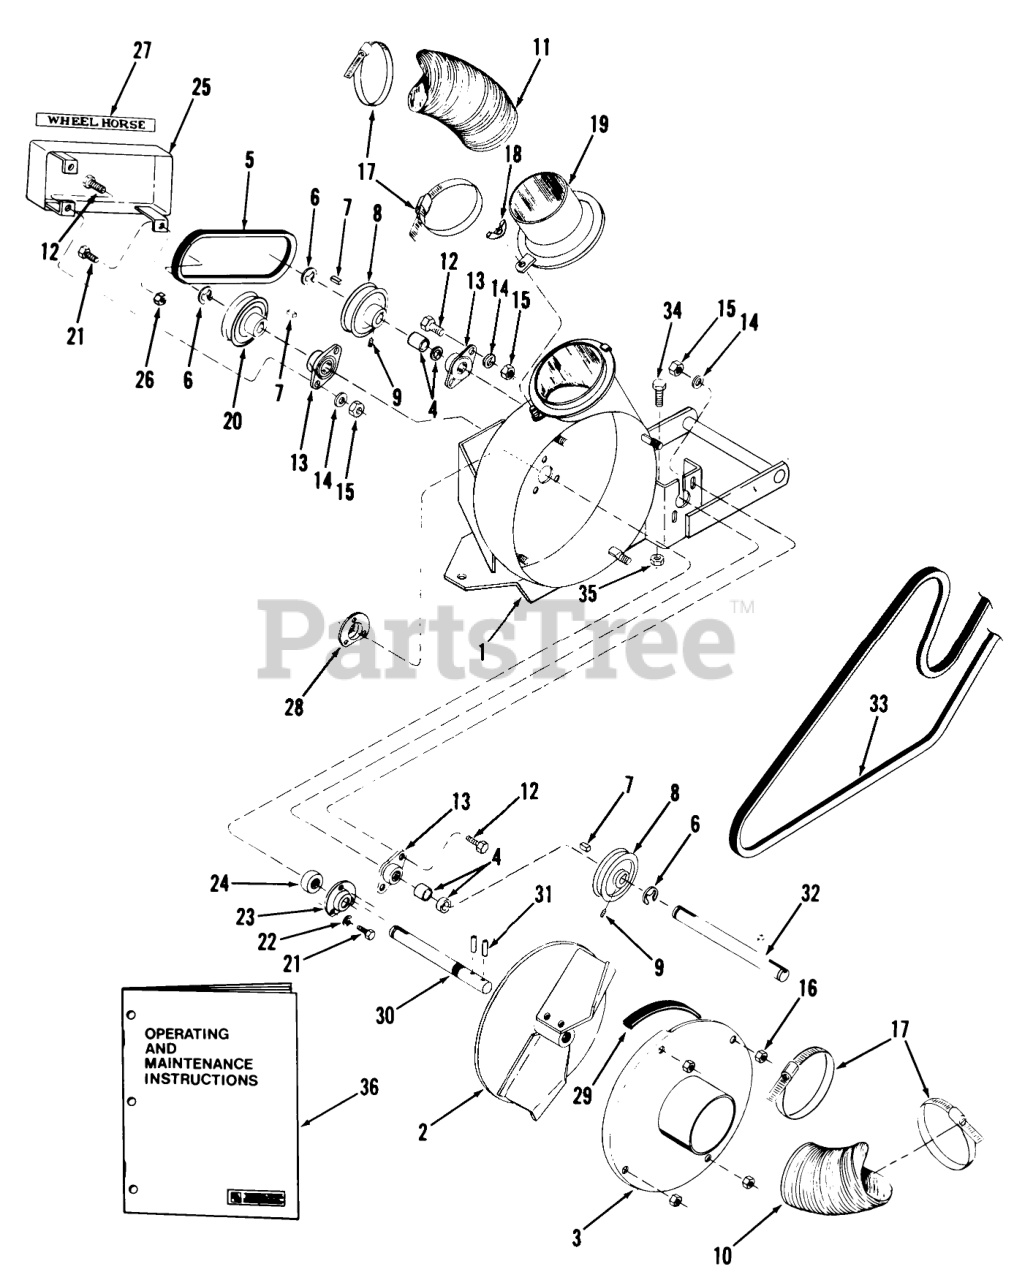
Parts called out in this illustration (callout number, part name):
1	Rubber Ring 14MM Red
1	Impeller Housing-97-42VC02 Only
2	Impeller
3	Front Plate
4	SPACER
4	Spacer-Jackshaft (Thick), Input Side-07-42VC01
4	Spacer-Jackshaft (Thin), Impeller Side-07-42VC01
5	V-BELT
6	E-Ring 3/4
7	KEY
8	JACKSHAFT PULLEY
9	Set Screw
10	6" Dia. Hose x 51"
11	6" Dia. Hose x 51"
12	Bolt
13	BEARING-JACKSHAFT
14	Washer
15	Nut
16	Nut
17	CLAMP
18	WING NUT
19	TRANSITION HOSE
20	Impeller Pulley
21	Bolt
22	Washer
23	BEARING-CUP
24	BEARING-BALL
25	Rubber Ring 14MM Black
25	Belt Cover-97-42VC02 Only
26	Nut
27	DECAL-WHEEL HORSE
28	BEARING-CUP W/NUTS
30	SHAFT
31	ROLL PIN 1/4 X 1-1/4
32	JACK SHAFT
32	JACKSHAFT
33	BELT-VEE
34	H H C S
35	Nut
36	Operating and Maintenance Instructions-97-42VC01 Only
36	Operating and Maintenance Instructions-97-42VC02 Only
